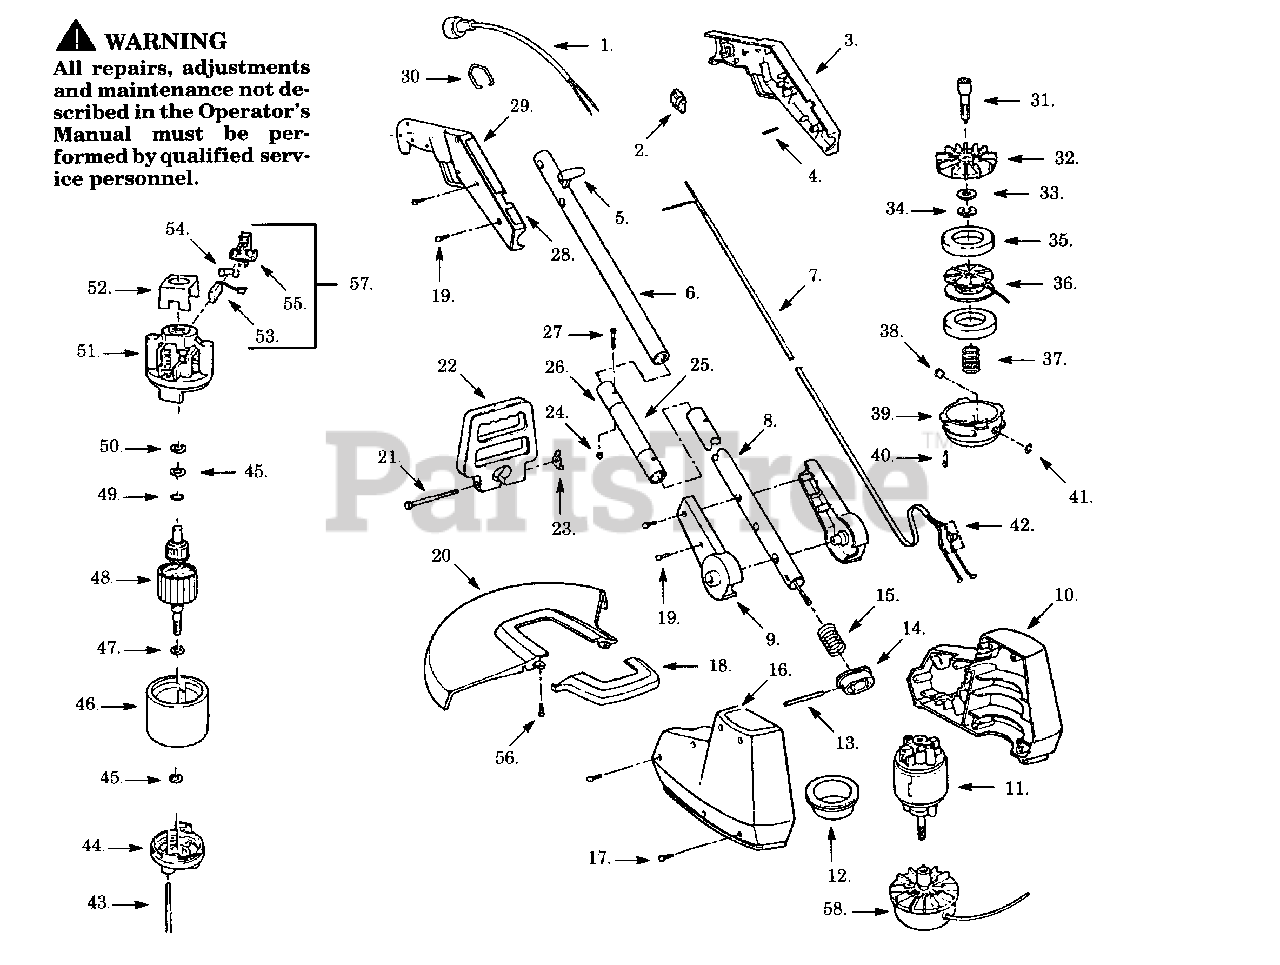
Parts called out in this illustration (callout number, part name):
1	Power Cord
2	Trigger Switch
3	R.H./L.H. Handle
4	Hinge Pin
5	Cable & Lever Ass'y.
6	Upper Tube
8	Lower Tube
9	R.H./L.H. Pivot
10	R.H./L.H. Housing
12	Air Baffle
13	Sleeve Pin
15	Sleeve Spring
16	Hsg. Top Label
18	Front Guard
20	Guard & Blade Ass'y.
22	Assist Handle
23	Wing Nut
24	Stop Nut
25	Warning Label (Not a serviceable part)
26	Outer Tube
28	Inch Cut Label
29	Handle Label
31	Drive Adapter
32	Rear Plate
34	Retaining Ring
35	Foam Pad
36	Spool & Line
39	Hub Ass'y.
40	Cotter pin
41	Wire Ring
42	Rectifier Kit
44	Endbell Ass'y. (Drive)
46	Field Ass'y.
47	Retaining Ring
48	Armature Ass'y.
49	Retaining Ring
51	Endbell Ass'y. (Brush)
52	Insulator
54	Brush Spring
55	Brush Holder
57	Brush Kit (Incl. 53,54,55)
58	Cutting Head Ass'y.
